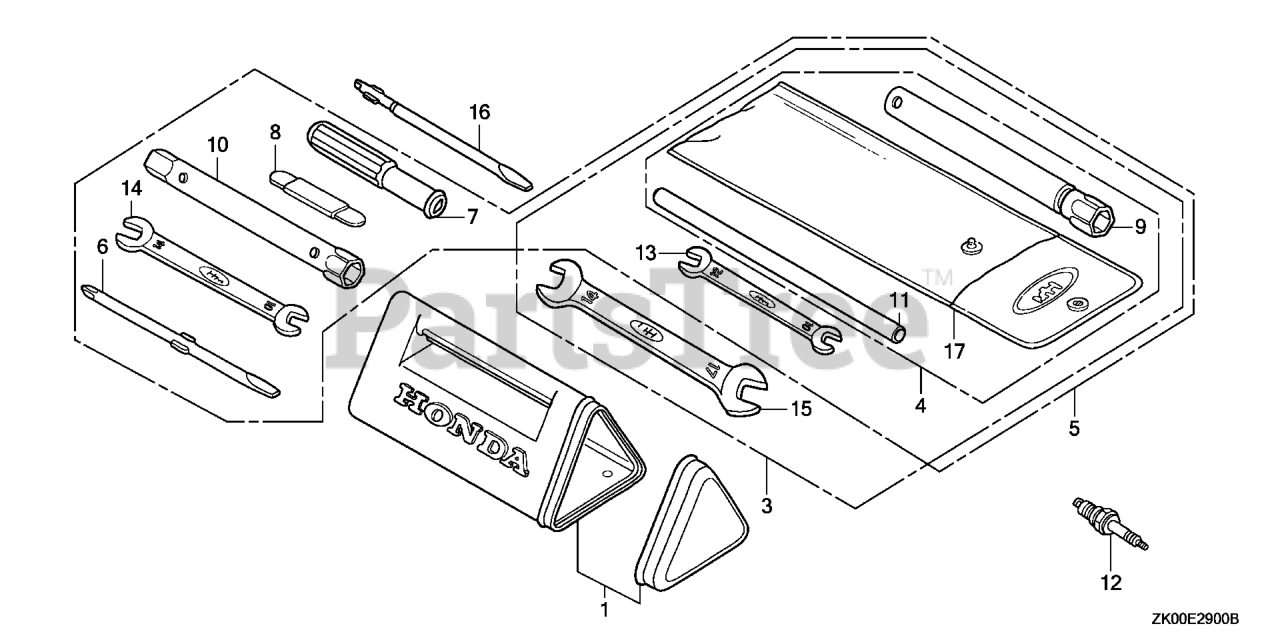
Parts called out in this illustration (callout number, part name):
5	BAG SET, TOOL
6	SCREWDRIVER (NO.2 PHILLIPS -)
8	GAUGE ASSY., THICKNESS
9	WRENCH, SPARK PLUG
10	WRENCH, BOX
11	HANDLE, BOX WRENCH (NOT AVAILABLE)
13	WRENCH (10X12) (OPEN END)
14	WRENCH (10X14) (OPEN END)
17	BAG, TOOL (230MM)
